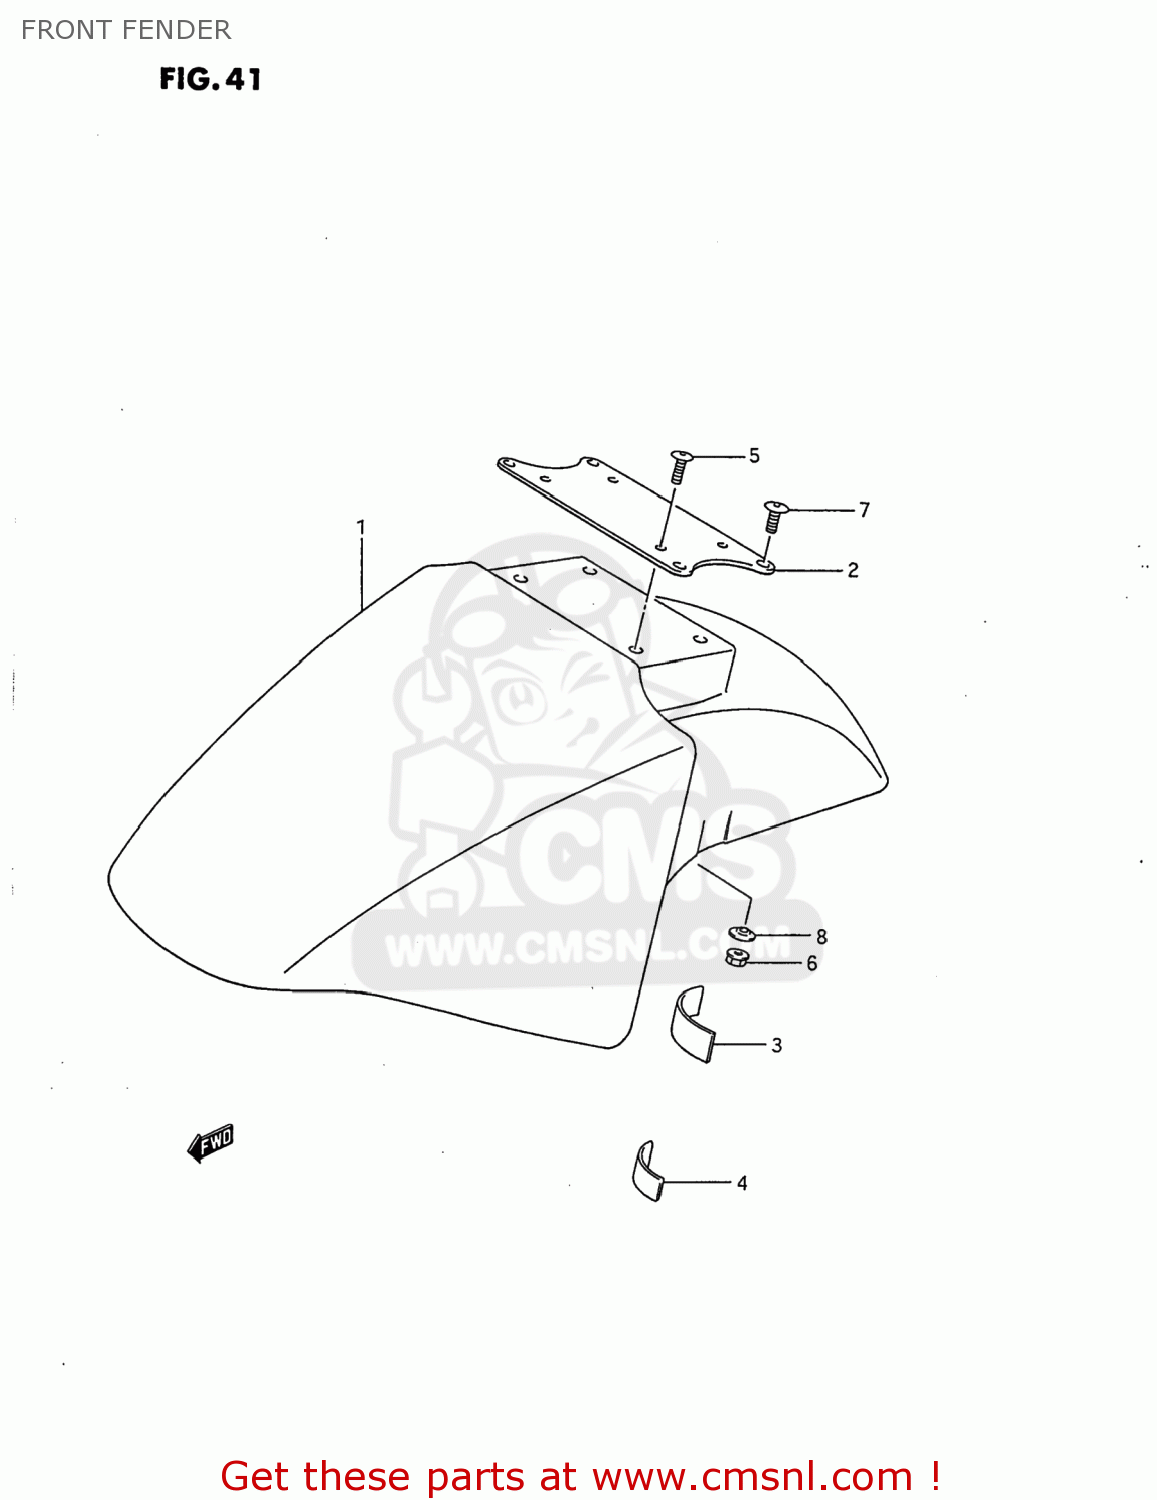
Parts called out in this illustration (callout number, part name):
1	FENDER,FR
2	BRACE,FR FENDER
3	CUSHION,FRONT FENDER
4	CUSHION
5	SCREW
6	NUT
7	SCREW(6X12)
8	WASHER
